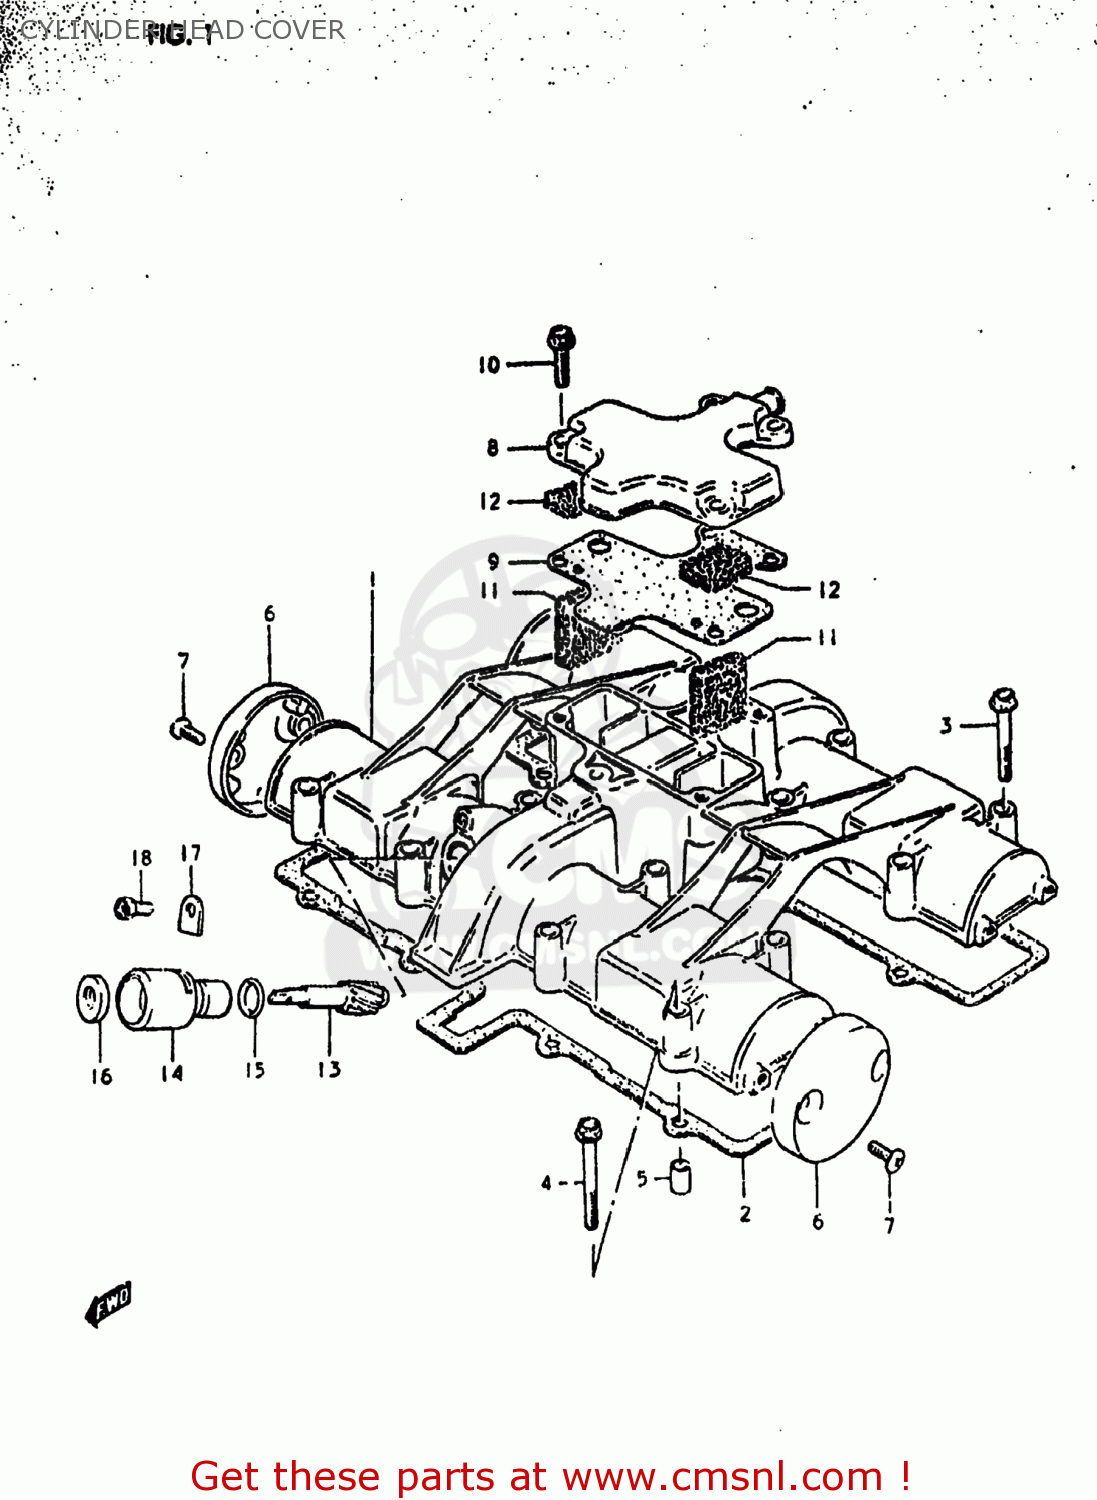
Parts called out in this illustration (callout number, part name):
1	COVER,CYLINDER HEAD
2	GASKET,CYLINDER HEAD COVER (MCA)
3	BOLT
4	BOLT,UNDER
5	PIN(6.2X8X11)
6	CAP,CYLINDER HEAD COVER
7	SCREW
8	COVER,BREATHER
9	GASKET (MCA)
10	BOLT,REAR
11	COVER,BREATHER
12	SEPARATOR,OIL BREATHER
13	GEAR,TACHOMETER DRIVEN
14	SLEEVE,TACHOMETER DRIVE
15	SEAL,TACHOMETER DRIVEN
16	SEAL,OIL(5X12X8)
17	PLATE,TACH DRIVE GEAR SLEEVE
18	SCREW(5X12)
